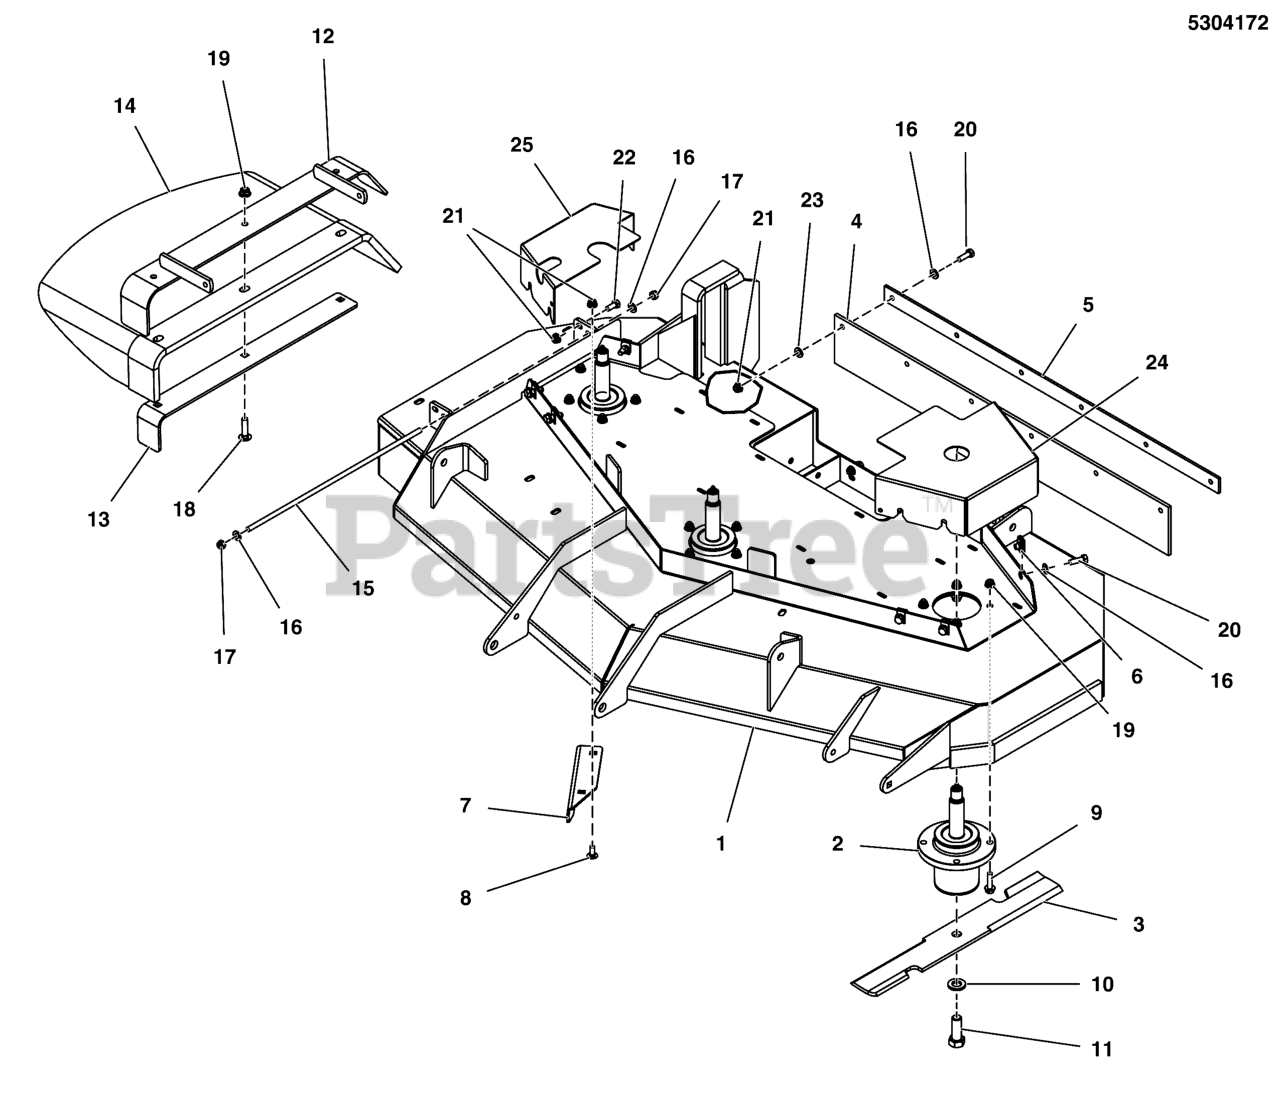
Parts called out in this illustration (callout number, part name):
1	DECK SHELL W/ DECALS, SS200-52
2	SPINDLE ASSM, ALUMINUM, LONG SHAFT
3	BLADE, 18 X .25 X 2.5, 1 X 3.5 (SET OF THREE)
4	FLAP, STRIPER, 61" DECK, IS3100, S200X
5	PLATE, SUPPORT - BLKV
6	BODY CLIP, 5/16-18-7GA MATERIAL
7	PLATE, DEFLECTOR, 52 DECK - BLK
8	BOLT, 5/16-18 X 3/4, CARRIAGE, GD5, CZ
9	BOLT, 3/8-16 X 1-1/4, FLANGE, GD 5, CZ
10	WASHER, BLADE BOLT, 9/16" F436, CZ
11	BOLT, 5/8-11 X 1-3/4 GD8
12	WELD, MOUNT, DISCHARGE CHUTE - BLK
13	SUPPORT, DISCHARGE CHUTE - BLK
14	CHUTE, RUBBER DISCHARGE (5104442)
15	ROD, MOUNT, CHUTE, 61, CZ
16	WASHER, 5/16" SAE
17	NUT, 5/16-24 HEX NYLON LOCK
18	BOLT, 3/8-16 X 1-1/2, CARRIAGE, GD5, CZ
19	NUT, 3/8 - 16 HEX NYLOCK FLANGE
20	BOLT, 5/16-18 X 1" GRD5 YZ
21	NUT, 5/16-18 HEX NYLOCK FLANGE NUT
22	BOLT, 5/16-18 X 3/4 GD5
23	5/16" PUSH-ON NUT RETAINER, STL, CZ
24	GUARD, LH 52 DECK, STAND ON - RED
25	GUARD, RH 52 DECK, STAND ON - RED
